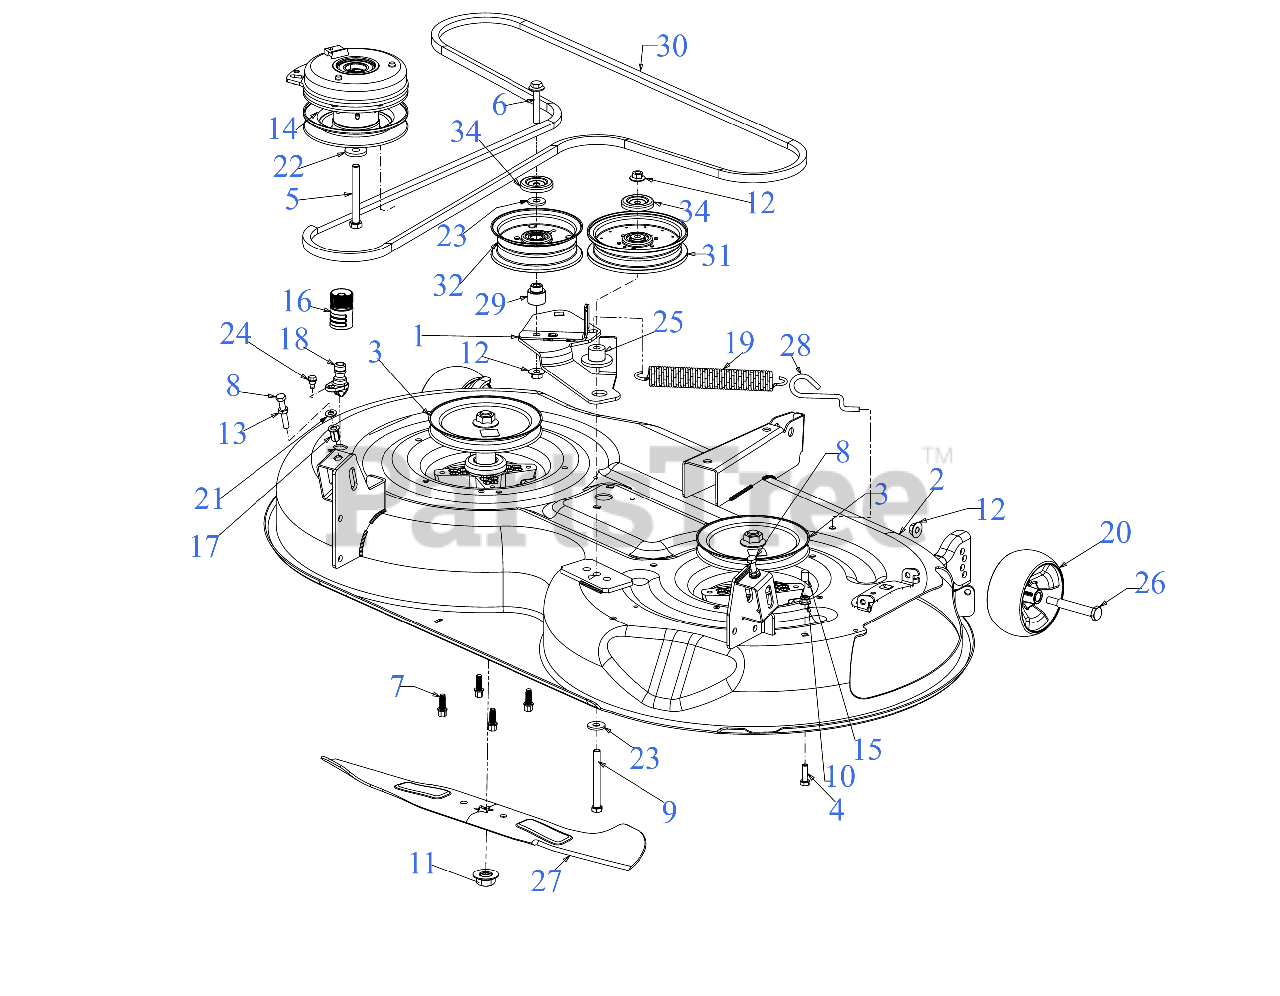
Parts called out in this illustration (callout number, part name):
1	BRACKET ASSEMBLY-DECK IDLER
2	46" DECK SHELL
3	SPINDLE ASSEMBLY
4	SCREW 5/16-18 x 1.0 GR5
5	SCREW 7/16-20 x 3.5 GR5
6	SCREW 3/8-16 x 2.25 GR5
7	SCREW 5/16-18 x .875
8	SCREW-FULL THREAD 5/16-18 GR5
9	SCREW 3/8-16 x 3.50 GR5
10	FLANGE LOCK NUT 5/16-18
12	FLANGE LOCK NUT
14	ELECTRIC PTO CLUTCH
16	WATER NOZZLE ADAPTER
17	NUT RIVET 5/16-18
18	DECK WASH NOZZLE
19	EXTENSION SPRING
20	DECK WHEEL
20	WHEELS-DELUXE 5"
21	FLAT WASHER .344 x .62
22	FLAT WASHER .445 x 1.248 x .170
23	FLAT WASHER .406ID X1.0 OD
24	SHOULDER SCREW 1/4-20 x .50
25	DOUBLE SHOULDER SPACER
26	SHOULDER BOLT .50 x 2.5 x 3/8 -16
27	23.25" BLADE (HIGH LIFT)
27	Cub Cadet 46" BLADE SET
27	Genuine Factory Parts 46" HI LIFT BLADE SET
28	DECK SPRING HOOK
29	SHOULDER SPACER
30	V-BELT A SEC x 120.8
30	Cub Cadet 46" RZT DECK BELT
30	Troy-Bilt 46" RZT DECK BELT
31	FLAT IDLER PULLEY
32	IDLER PULLEY 4.50" DIA
34	IDLER PULLEY CAP
